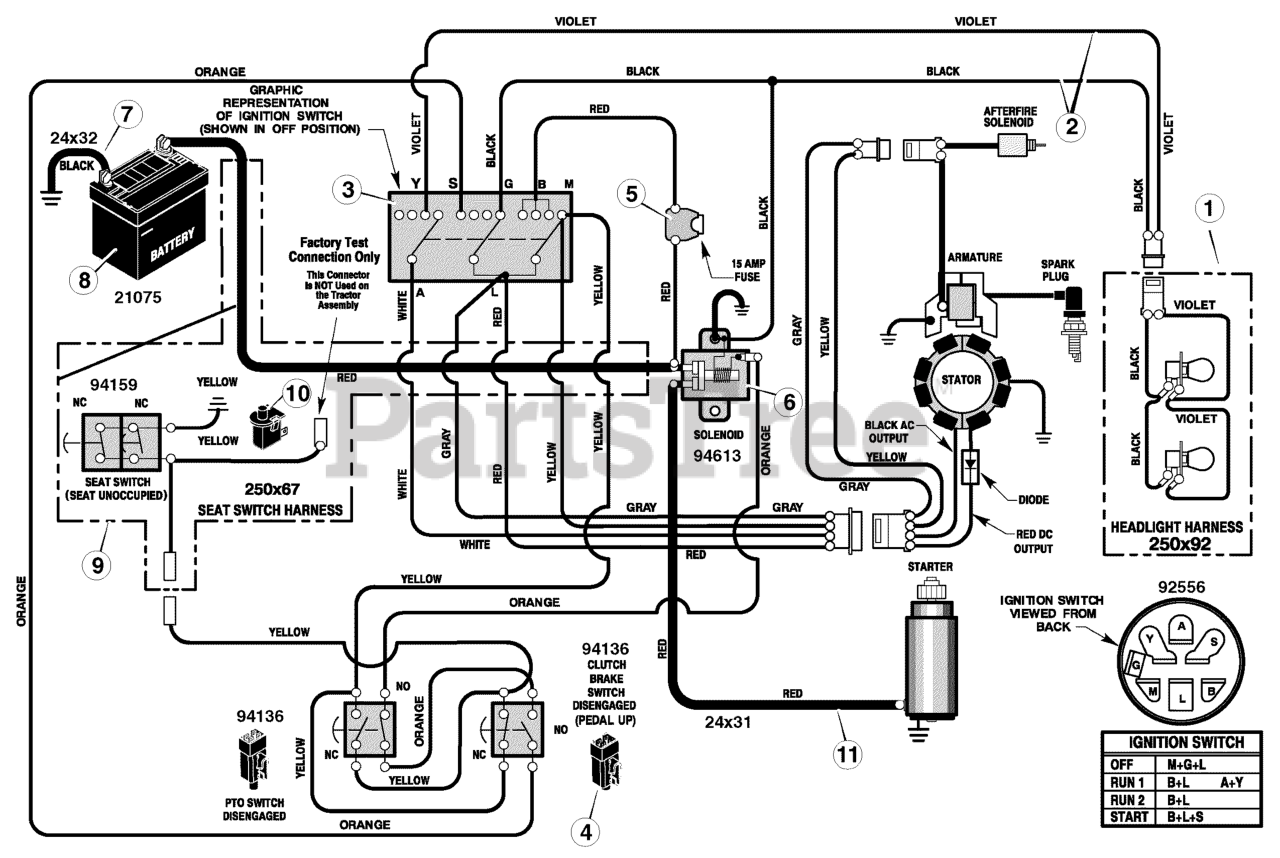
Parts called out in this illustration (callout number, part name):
1	Harness, Light Wire
1	Socket, Light
1	Bulb, Light
2	Harness, Chassis Wire
3	Switch, Ignition
3	Key, Ignition
3	Nut, Hex
3	Cap, Ignition
4	Switch, Limit
5	Fuse
5	Holder, Fuse
6	Solenoid
6	Screw, Mounting
6	Locknut
7	Cable, Battery Ground
7	Screw, Ground Cable
8	Battery
8	Bolt, Carriage
8	Wingnut
9	Harness, Seat Switch Wire
10	Switch, Seat Sensor
11	Cable
